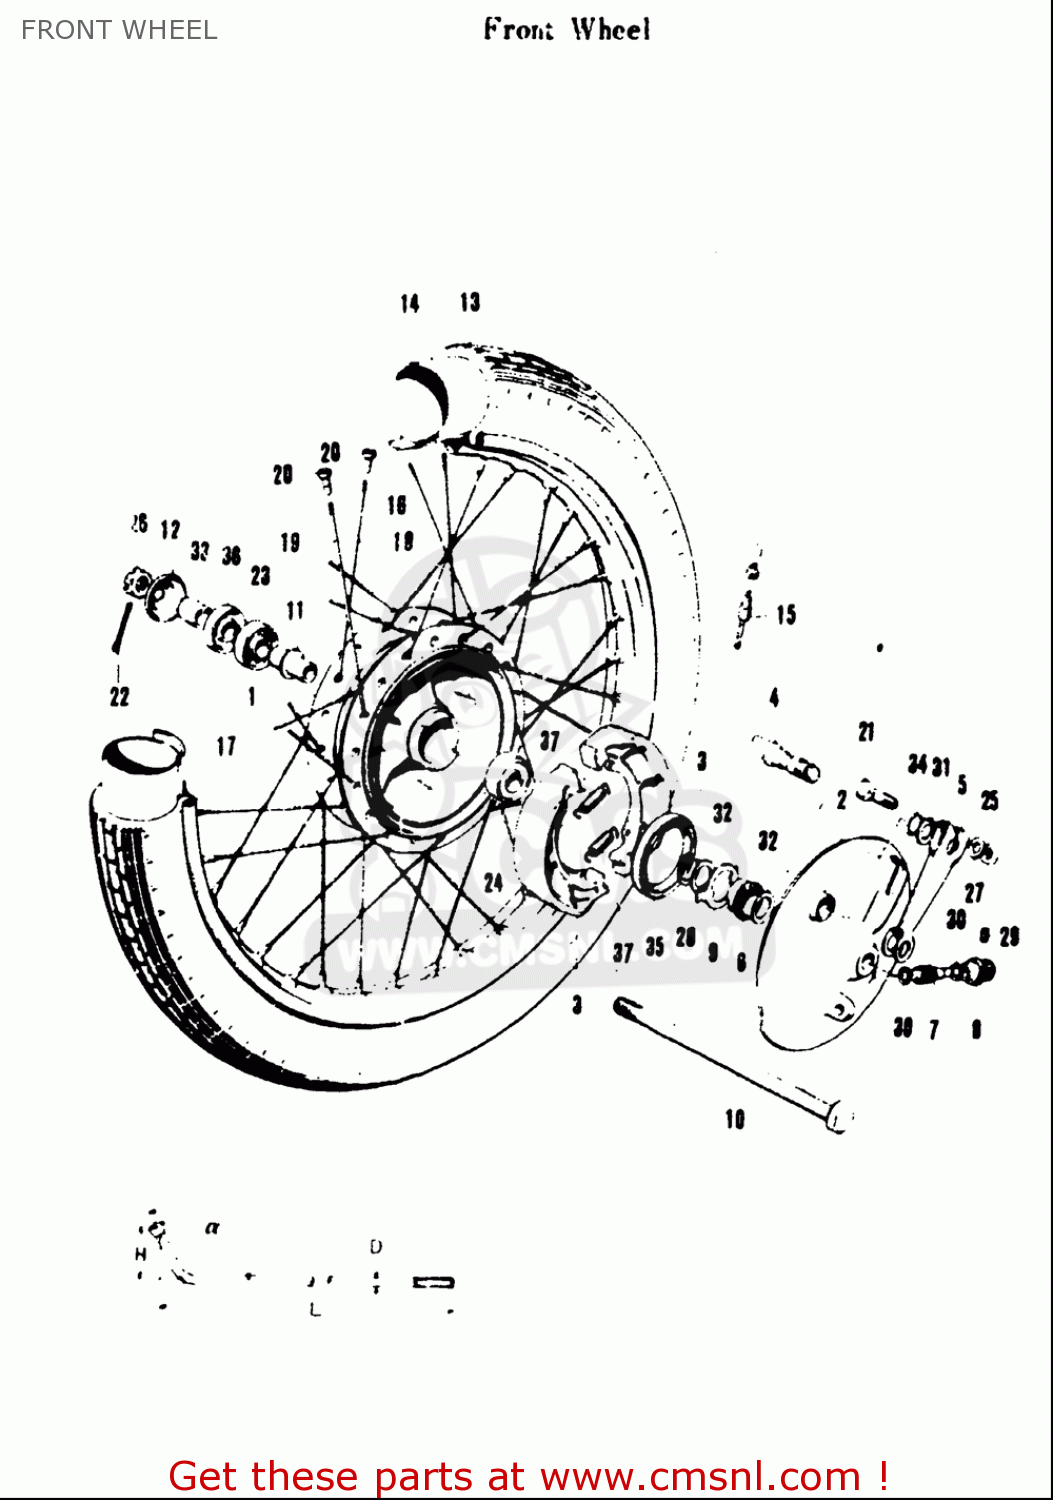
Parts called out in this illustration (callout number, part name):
5	LEVER,FR BRAKE CAM
6	GEAR,SPEEDOMETER(NT:24)
9	DRIVER,SPEEDOMETER GEAR
16	PROTECTOR,WHL INR TUBE
17	RIM,WHEEL(1.40X17)
23	BEARING
24	BEARING
25	NUT
27	WASHER
28	CIRCLIP
29	SCREW
30	WASHER(5.1X9X0.4)
31	WASHER(12.5X20X1)
32	WASHER(18.5X24X1)
33	SPACER(12X18X19.4)
34	O RING(D:2.5,ID:11.4)
36	OIL SEAL(17X38X5)
